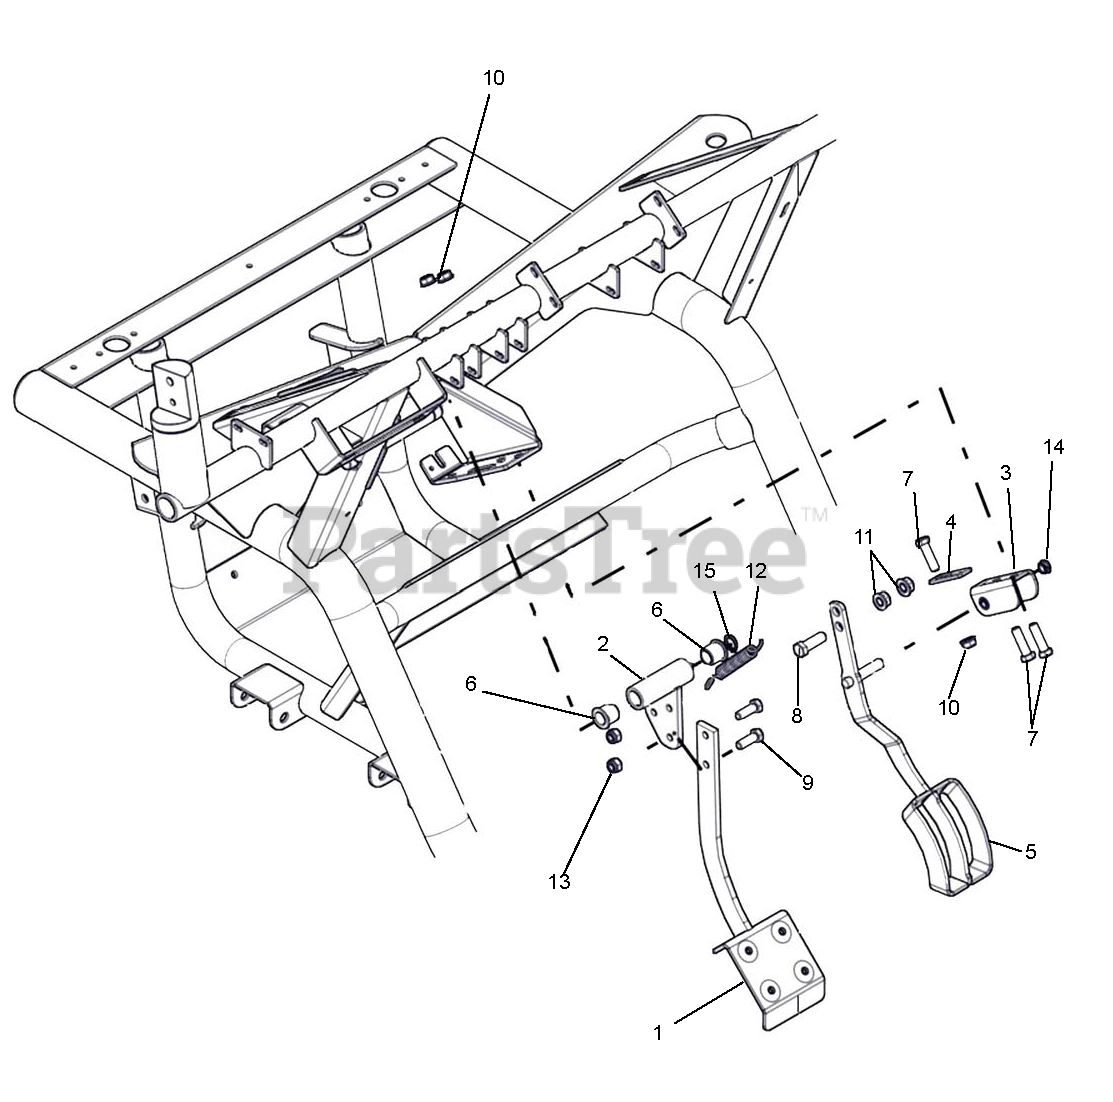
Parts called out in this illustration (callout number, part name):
1	BRAKE PEDAL ASM
2	BRAKE PEDAL PIVOT WELDMENT
3	GAS PEDAL MOUNT
4	GAS PEDAL ADJUSTMENT PLATE
5	WLDT, GAS PEDAL
6	BUSHING 3/4ODX5/8IDX3/4 FLG HD
7	@BLT-HEX .31-18X1.25 GR5 YWZC
8	@BLT-HEX .38-16X1.25 GR5 YWZC
9	@BLT-HEX .31-18X1.00 GR5 YWZC
10	@NUT-LK-TOP-FLG .31-18 YWZC
11	@NUT-LK-TOP-FLG .38-16 YWZC
12	SPRING EXT .5OD .075W 2.75LG
13	@NUT-LK-NYL .312-18 YWZC
14	BUSHING NYLON 3/8ID (SNAP IN)
15	SNAP RING, .625 X .035 EXT
